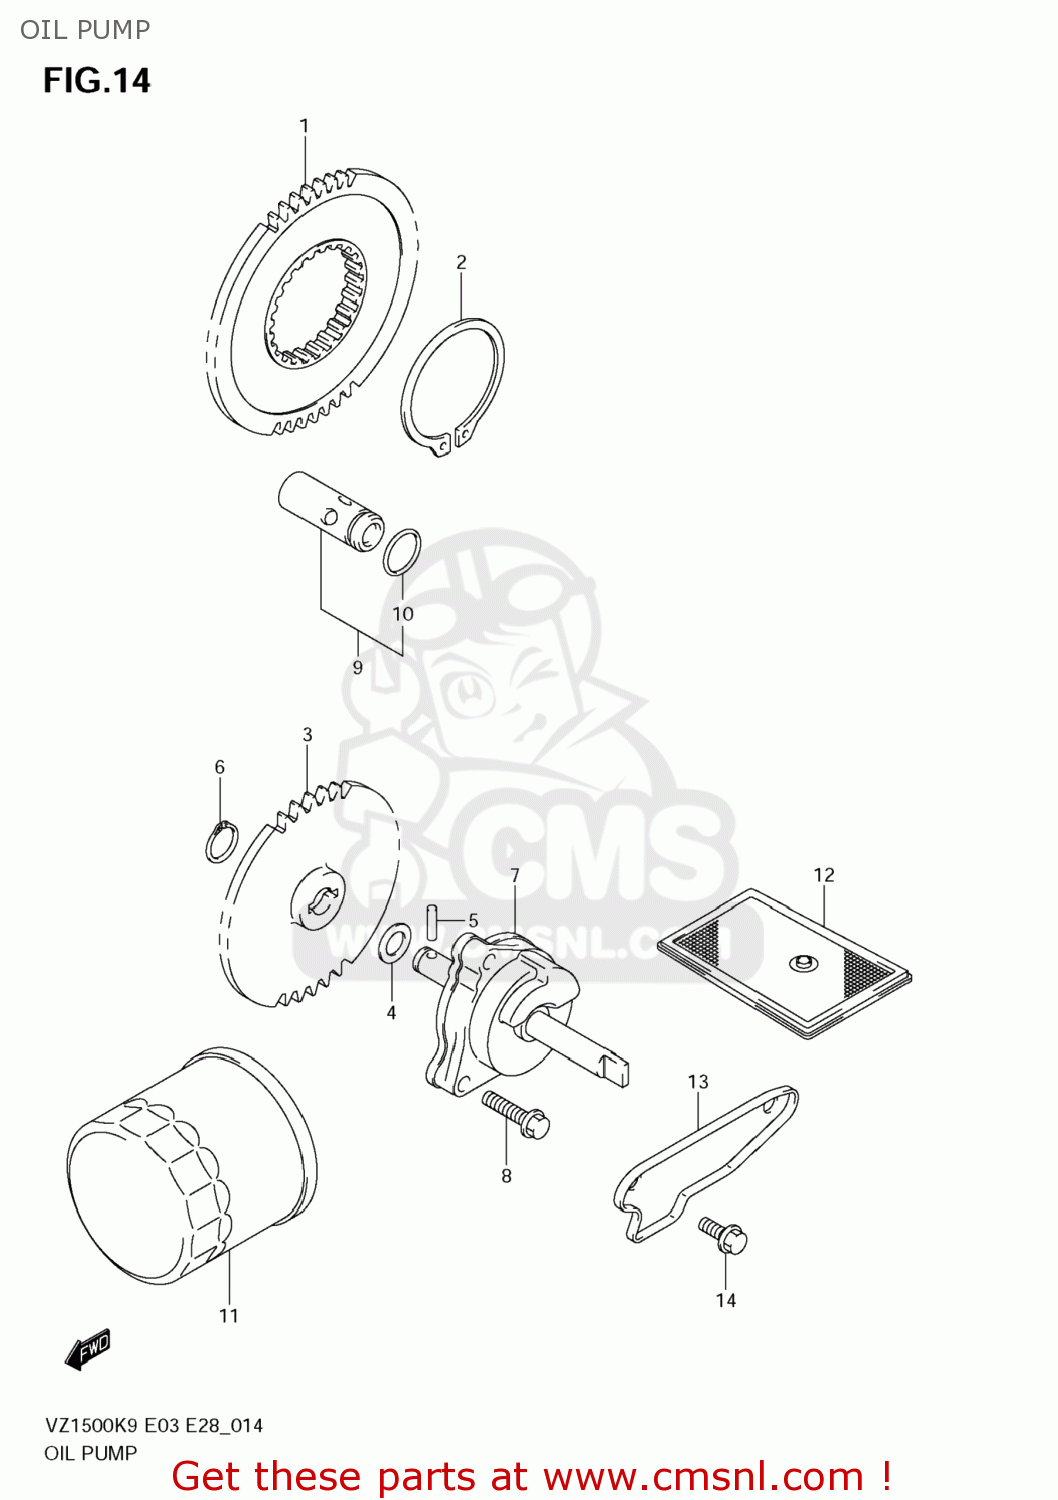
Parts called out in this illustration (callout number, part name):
1	GEAR,OIL PUMP DRIVE
2	CIRCLIP
3	GEAR,OIL PUMP DRIVEN
4	SHIM(10X18X0.5)
5	PIN(4X15.8)
6	CIRCLIP
7	PUMP ASSY,ENGINE OIL
8	BOLT
9	VALVE ASSY,OIL RELIEF(7K)
10	O RING(D:1.9,ID:13)
11	FILTER ASSY,EN
12	STRAINER,ENGINE OIL
13	CAP,OIL STRAINER
14	BOLT
